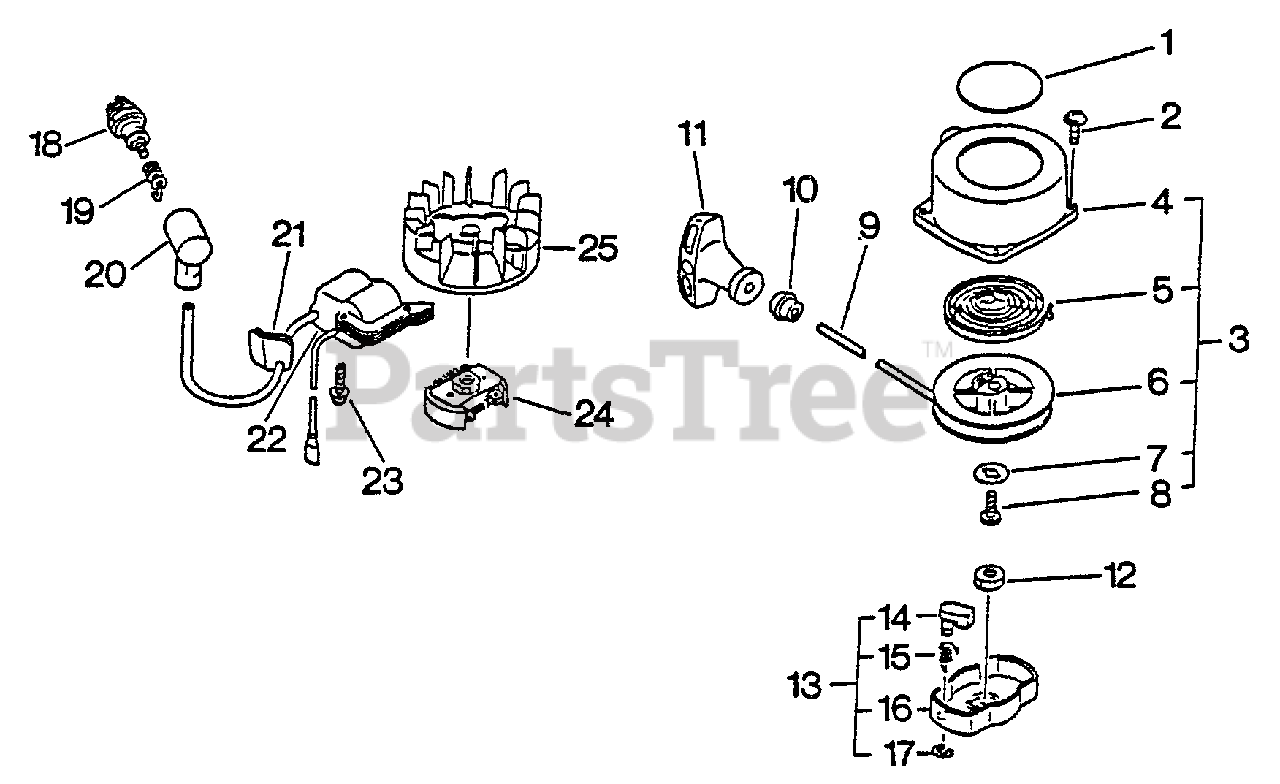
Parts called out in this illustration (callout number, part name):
1	LABEL, ECHO
2	SCREW 4×16
3	STARTER ASSY
4	CASE, RECOIL STARTER
5	SPRING, RECOIL
6	REEL, ROPE
7	WASHER
9	ROPE, STARTER
10	GUIDE, ROPE
11	GRIP, STARTER
12	NUT 8×1.25
13	STARTER PAWL ASSY
14	CATCHER, PAWL
15	SPRING, RETURN
16	PAWL, STARTER
17	E-RING 4
18	SPARK PLUG - BM6A
19	TERMINAL, SPARK PLUG
20	CAP, SPARK PLUG
22	COIL, IGNITION
23	SCREW 4×22
24	CLUTCH ASSY
25	FLYWHEEL
